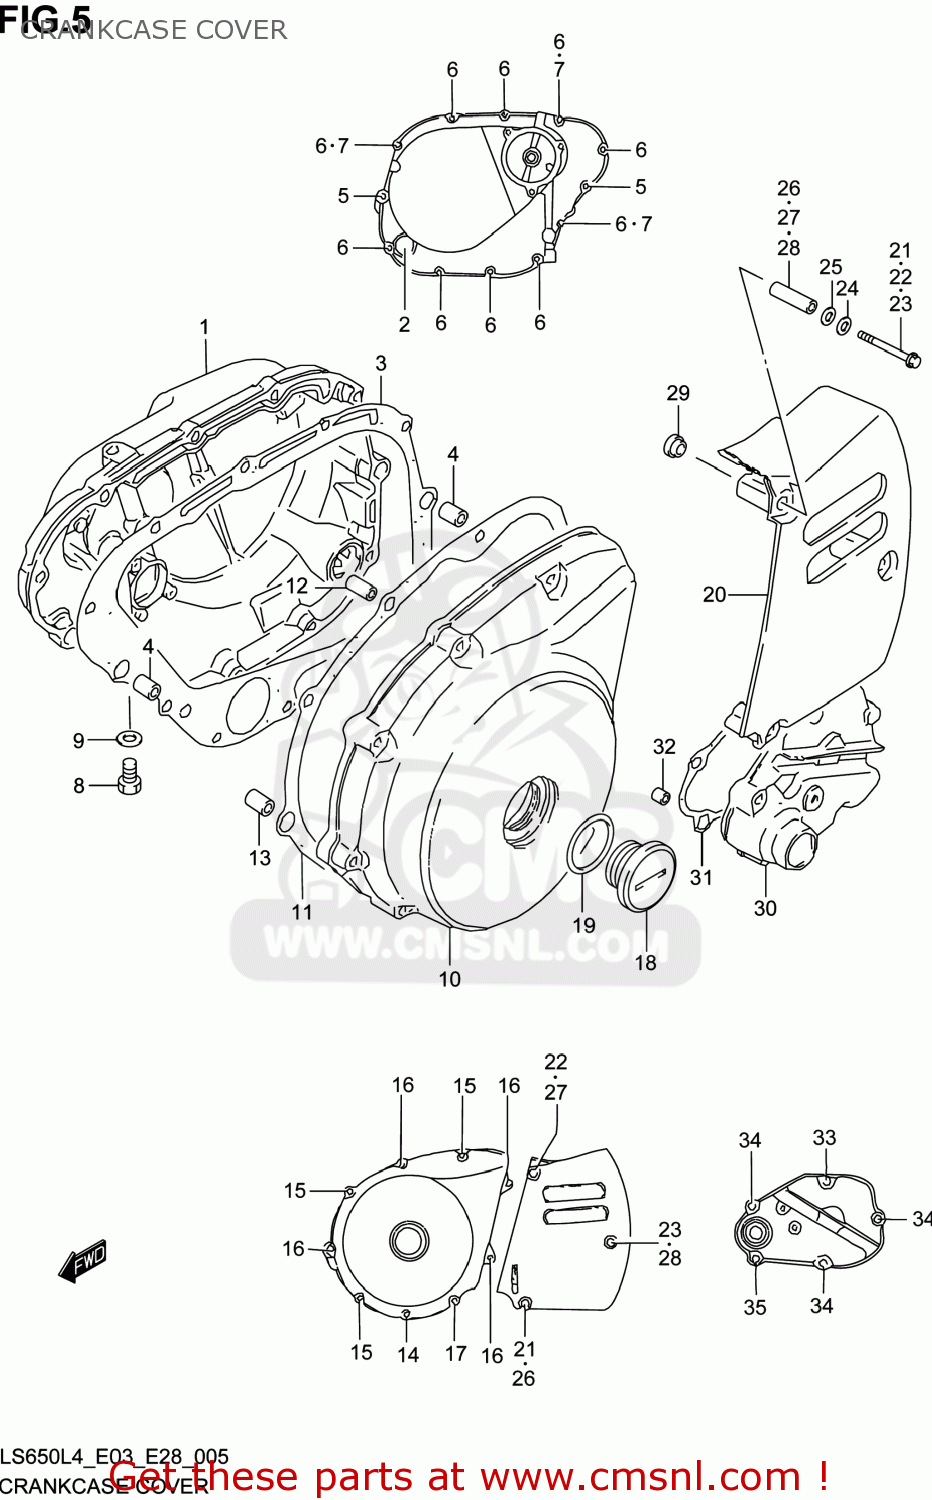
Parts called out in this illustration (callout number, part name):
1	COVER,CLUTCH
2	LENS,OIL LEVEL CHECK
3	GASKET,CLUTCH COVER (NAS)
4	PIN
5	BOLT(6X35)
6	BOLT(6X25)
7	GASKET(5.8X13X1.2) (NAS)
8	PLUG,12X9
9	GASKET(12.1X16.2X3.7) (NAS)
10	COVER,GENERATOR
11	GASKET,GENERATOR COVER (NAS)
12	PIN
13	PIN
14	BOLT(6X25)
15	BOLT(6X35)
16	BOLT(6X45)
17	BOLT(6X50)
18	PLUG,36X10
19	O RING(D:3.1,ID:32.7)
20	COVER,ENGINE SPROCKET
21	BOLT(6X45)
22	BOLT(6X50)
23	BOLT(6X55)
24	WASHER(6.5X14X1.6)
25	WASHER(8.7X15X2.1)
26	SPACER(6.5X9X31.5)
27	SPACER(6.5X9X38.3)
28	SPACER(6.5X9X41.3)
29	WASHER(8.7X16X5)
30	COVER,GEAR SHIFT
31	GASKET,GEAR SHIFT COVER (NAS)
32	PIN
33	BOLT
34	BOLT
35	BOLT
